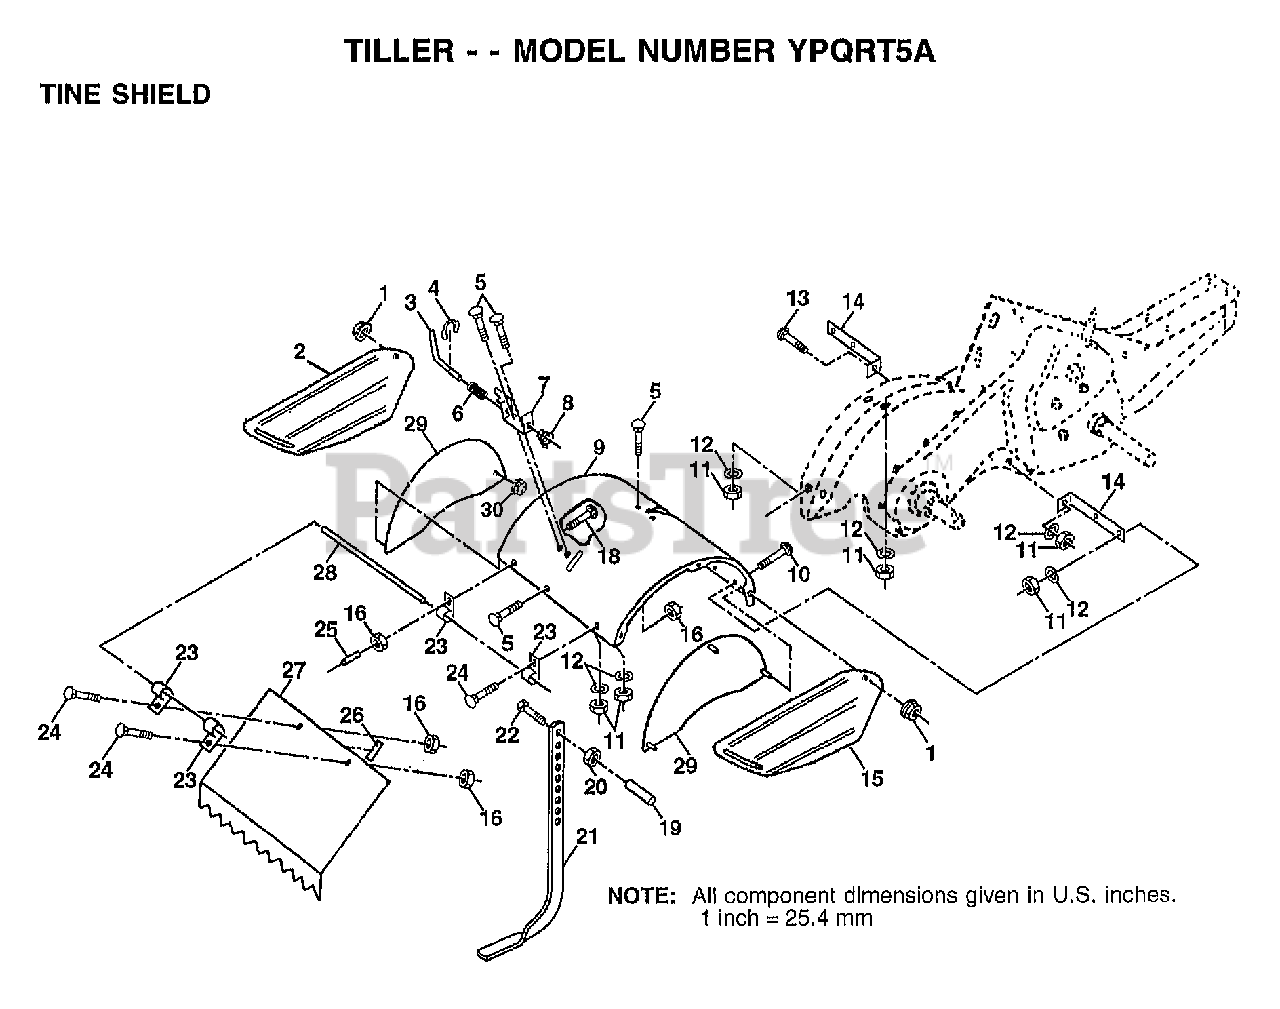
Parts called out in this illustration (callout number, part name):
1	NUT
2	SHLD.SIDE.OUTER.L
3	STAKE PIN TI
4	KLIP RING TI
5	BOLT
6	SPRING TI
7	LATCH BRACKET TI
8	SPRING CRT
9	SHIELD TINE
10	BOLT
11	NUT.HEX.5/16-18
12	LOCKWASHER
13	BOLT
14	BRKT SHIELD TINE
15	SHLD.SIDE.OUTER.R
16	NUT
18	BOLT
19	GRIP CRT
20	NUT.HEX.3/8-16UNC
22	BOLT
23	HINGE CRT
24	BOLT
25	VINYL CAP TI
26	PAD IDLER TI
27	"SHIELD,LEVEL"
28	PIN HINGE
29	SHIELD SIDE
